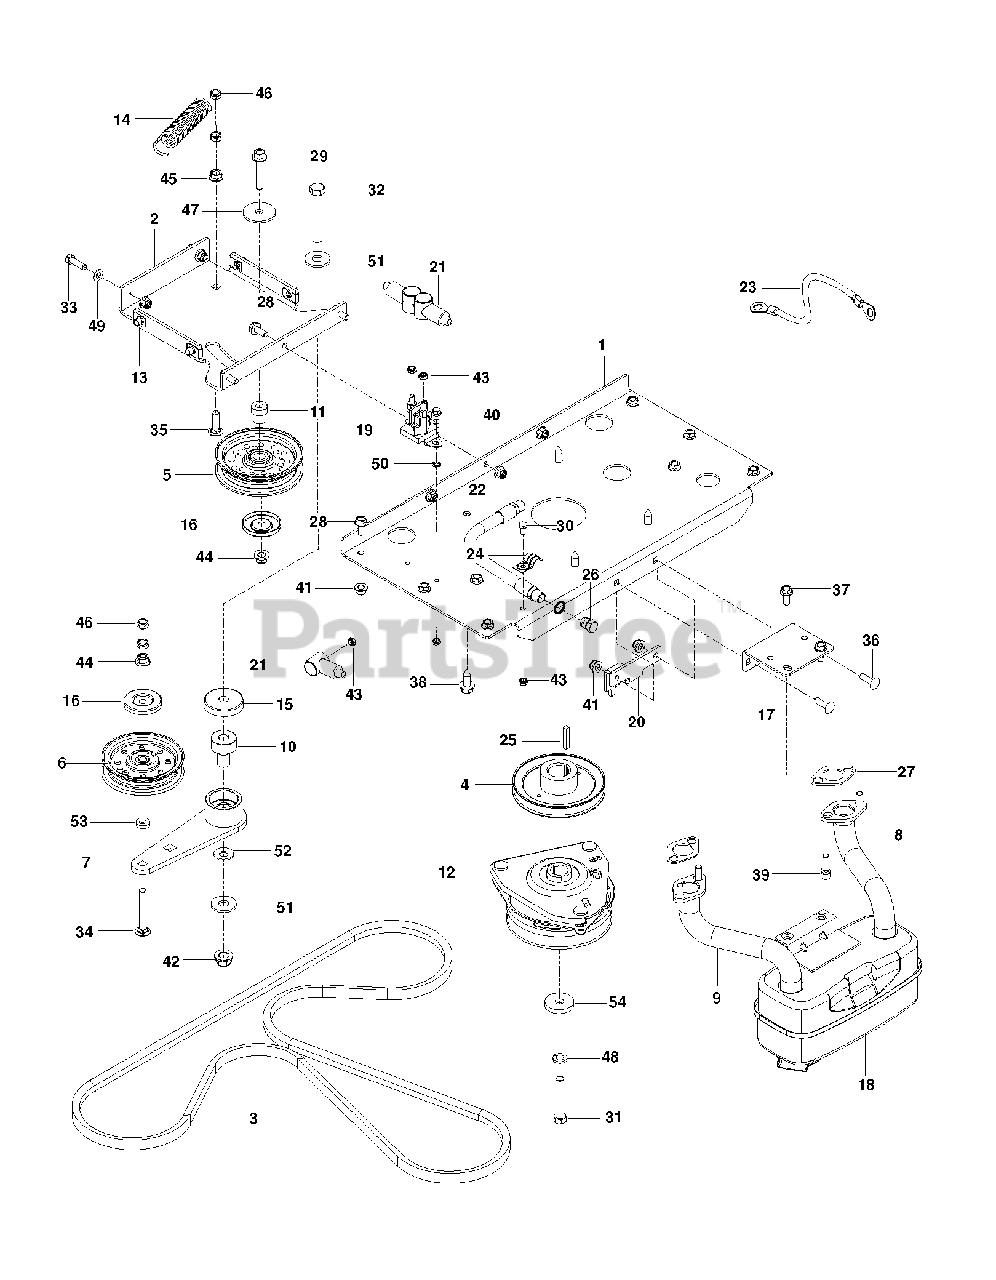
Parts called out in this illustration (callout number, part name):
1	PLATE, ENGINE, BLK
2	PLATE, IDLER, BLK
3	BELT, HYDRO, 3400
4	PULLEY.DRIVE.XMSN
5	IDLER PULLEY
6	FLAT IDLER PULLEY
7	ARM, IDLER, STEEL, W/BGS
8	Exhaust Pipe, RH CV18/20
9	Exhaust Pipe, LH CV18/20
10	PIVOT, BEARING
11	PIVOT, IDLER
12	CLUTCH ELECTRIC
13	U-CLIP 5/16-18 NUT RETAINER
14	SPRING, PUMP
15	SHIELD, DUST
16	DUST SHIELD
17	BRKT, MUFFLER, BLK
18	MUFFLER ASM TWIN
19	SOLENOID.W/BRASS.PLUNG
20	Stop Clutch Bracket
21	TERMINAL COVER
22	Oil Drain Hose Assembly
23	CABLE POSITIVE
25	KEY, 1/4 SQ X 1 1/4
26	Oil Drain Plug
27	Exhaust Gasket
28	HHFS 5/16-18 X 3/4
29	HHFS 3/8-16 X 2.0 GD 5
30	HCS 1/4-20.
31	Clutch Bolt, 7/16-20 X 2.5 Gr 5 24Hr
32	HCS 1/2C X 3 1/4
33	HCS 5/16C X 1
34	RHSNB 3/8-16 X 2.75
35	RHSNB 3/8-16 X 1-1/4
36	RHSSNB 5/16C X 1.0
37	SCREW
38	SCREW 3/8-16X1
39	SCREW.SOCKET HD.5/16-1
40	HWST 1/4C X 3/8
41	5/16-18 NYLOC FLANGE NUT
42	NUT, 1/2-13 HEX FLG NYLOC ZD
43	JAM NUT 1/4C
44	NUT 3/8-16 HEX FLG NYLOC ZD
45	NUT 3/8C WHIZ
46	NUT HEX 3/8-16 NYLON, THIN
47	WASHER, 3/8 SPEC
48	WASHER 7/16 LOCK
49	FLAT WASHER 5/16 SAE
50	WASHER 1/4 INT TOOTH
51	WASH USS FLAT 1/2
52	CONTACT BELLSPR 1/2
53	WASHER 3/8 X 3/4 X .187 TK
54	SPINDLE WASHER
